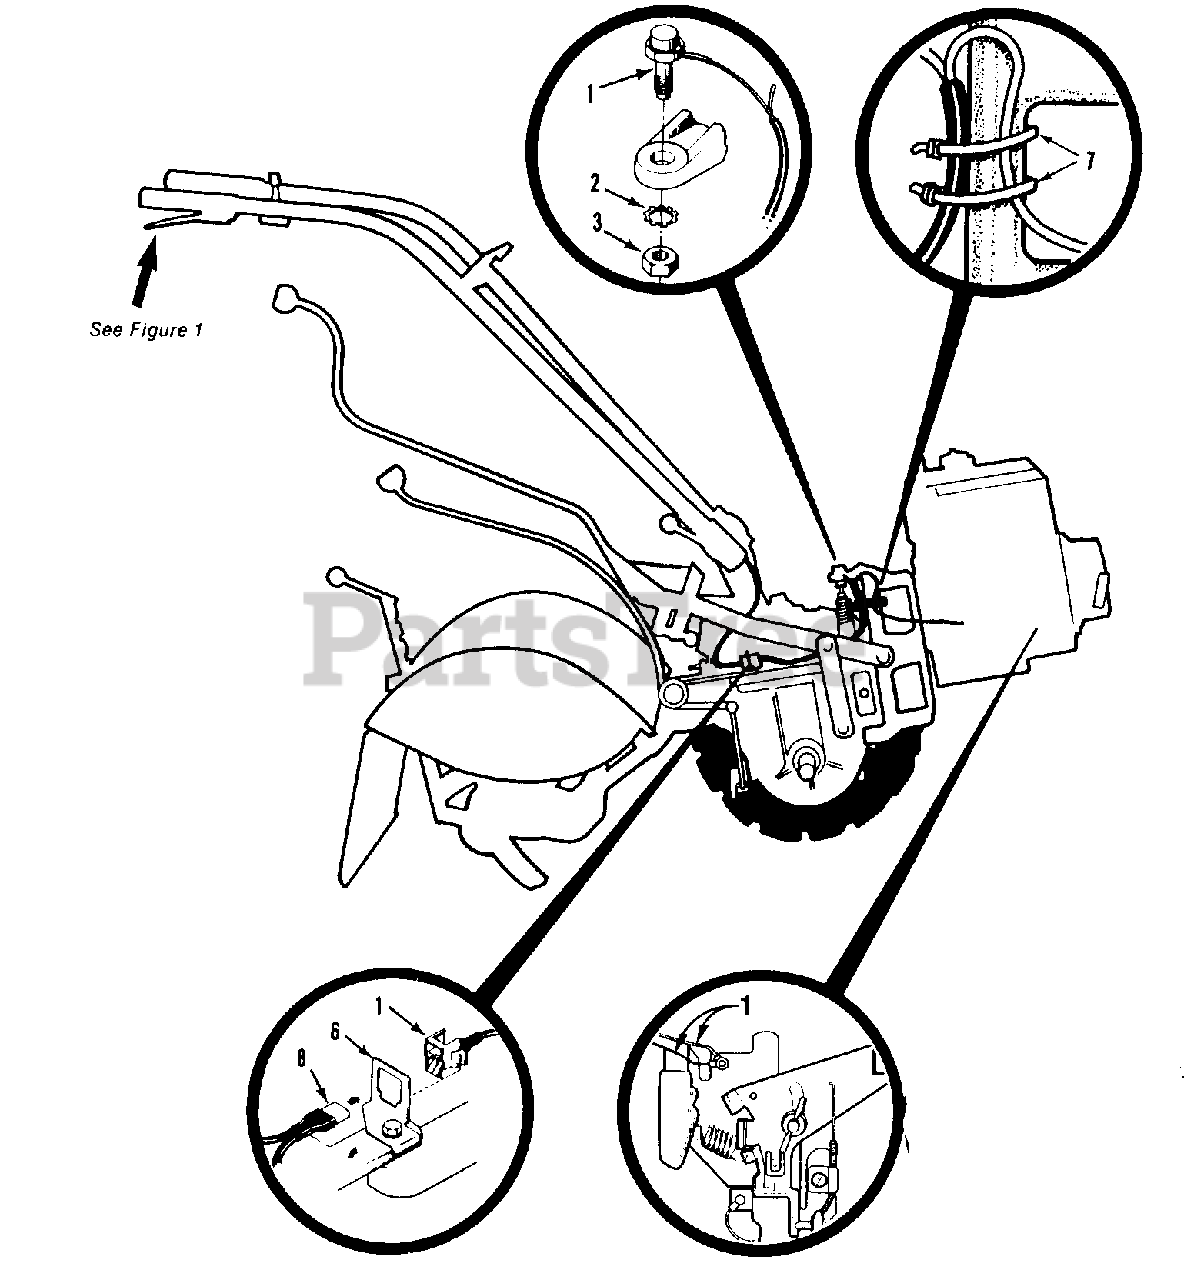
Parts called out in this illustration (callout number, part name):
1	Engine Wire Harness Assy-forward interlock system
2	Lockwasher - external tooth, 7/16"
3	Nut-hex, 7/16"-20
6	Clip-for plug connector
7	Tie-plastic
8	Handlebar Wire Harness Assy.
